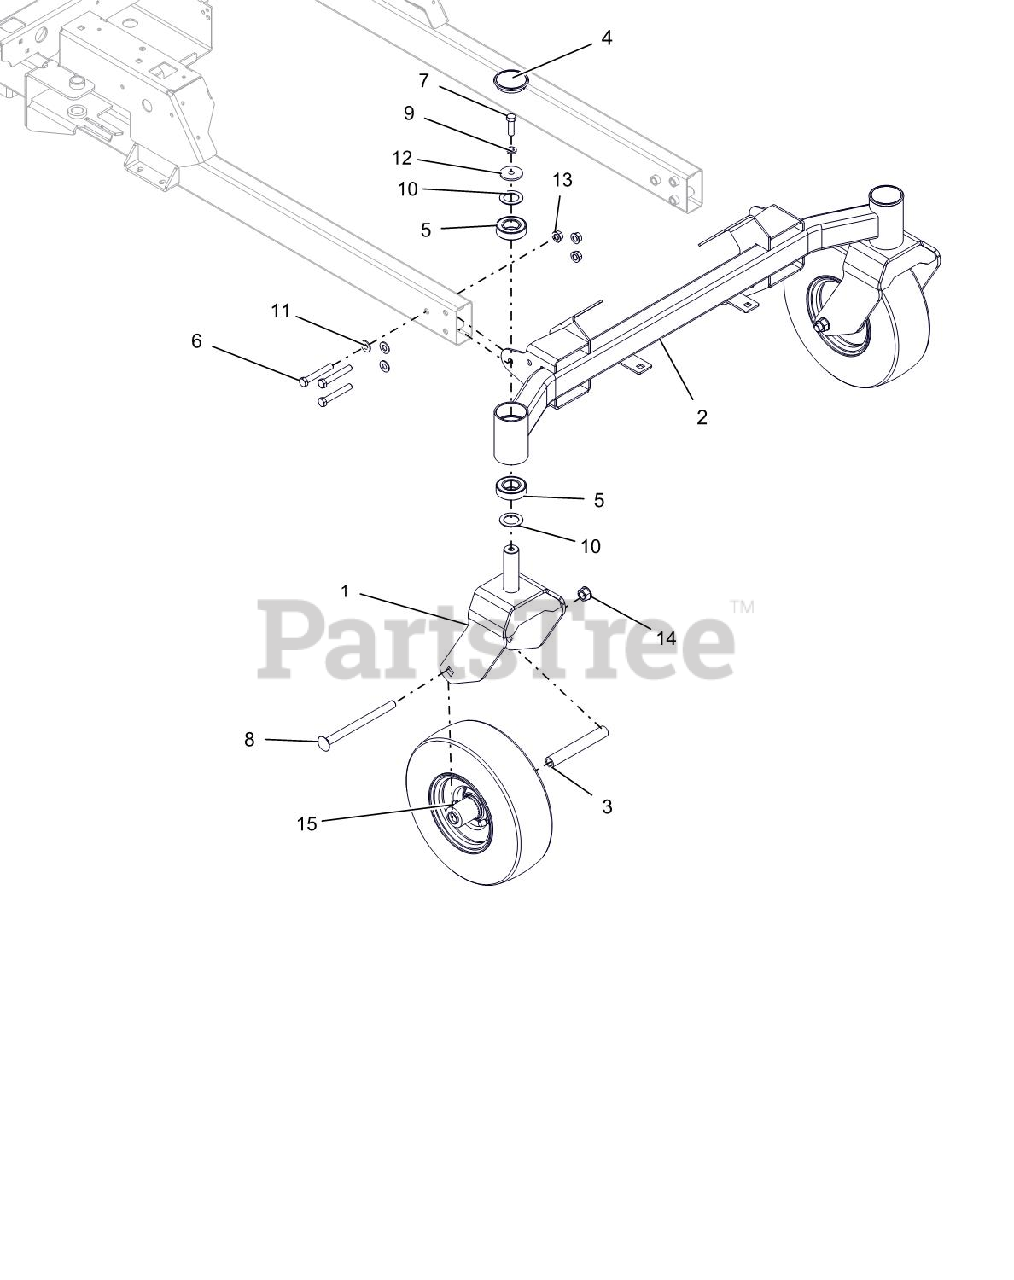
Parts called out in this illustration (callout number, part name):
1	WMT, CASTER FORK
2	WLDMT, AXLE FRONT
3	SPACER, ROLLED WHEEL
4	CAP, DUST
5	BRG,BALL 1.00X2.00X.563(1641)
6	BLT-HEX .38-16X2.50 GR8 YWZC
7	@BLT-HEX .38-16X1.25 GR5 YWZC
8	BLT-RDHDSQNK .50-13X6.50 GR5 Y
9	@WSHR-LK .38X.094 REG YWZC
10	WSHR-HRD-THRS 1.007X1.542X.062
11	WSHR-HDND .406X.812X.055
12	WSHR-FL-STL .380X1.50X.125YWZC
13	NUT-LK-TOP-FLG .38-16 GRG YWZC
14	NUT-LK-TOP-FLG .50-13 YWZC
15	ASM, WHL/TIRE 11X4.00-5
